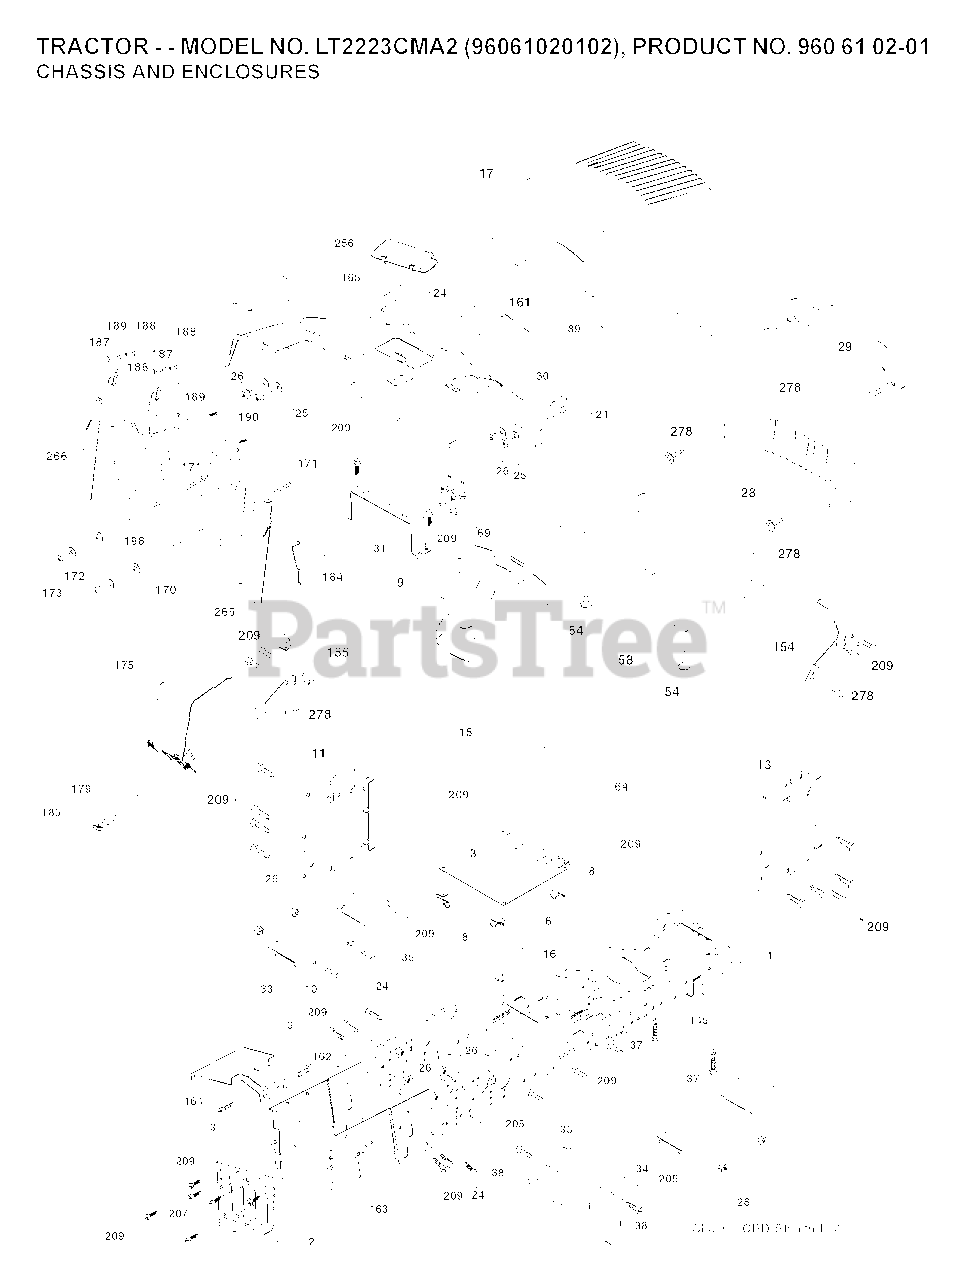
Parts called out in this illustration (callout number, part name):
1	CHASSIS
3	SCREW 3/8-16X3/4
8	CLIP,INSULATOR
10	BOLT D
13	PANEL DASH RH
16	NUT
25	WASHER
26	NUT
31	BRACKET SUPPORT FENDER
54	SCREW.WSHD.HEX10-32X5/8
58	DUCT HOOD
69	SCREW.HI-LO.CONSOLE
145	ROD.PIVOT.HOOD
161	EXTRUSION BUMPER
164	SUPPORT
171	BOLT
172	WASHER
186	LATCH ASSY
187	WELDNUT
189	LOCKWASHER
207	SCREW, 5/16-18 X 1/2
209	SCREW, 3/8-16X3/4
278	SCREW
